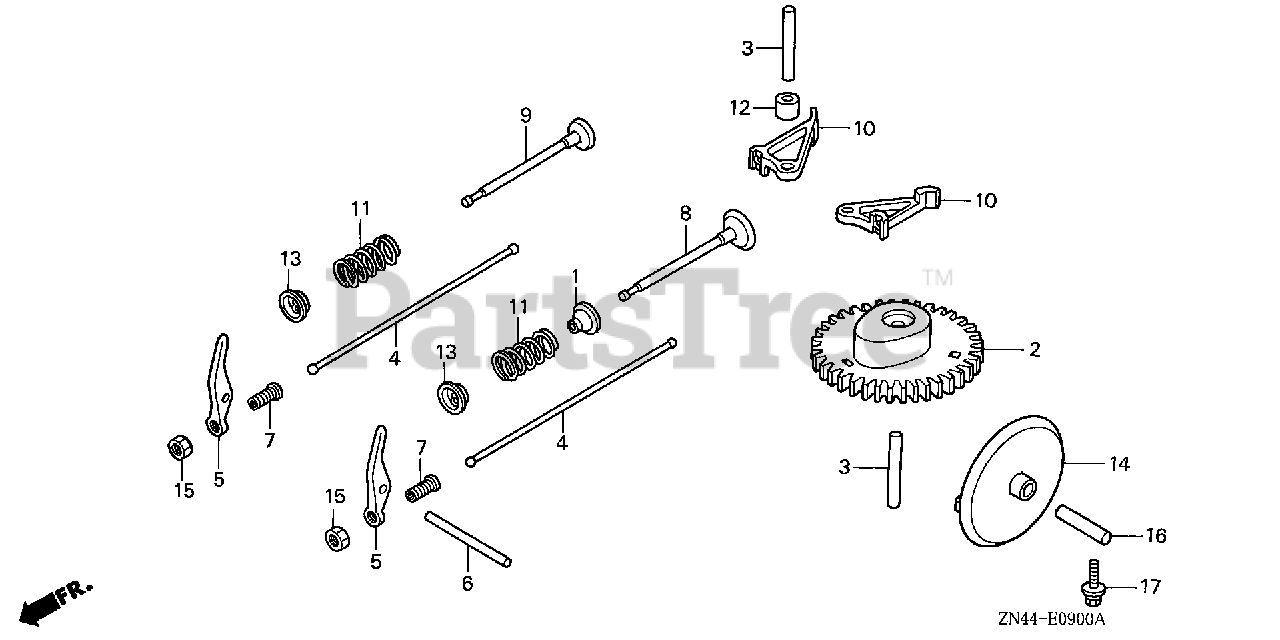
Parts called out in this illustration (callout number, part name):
1	SEAL, VALVE STEM
2	CAMSHAFT ASSY.
3	PIN, OIL PUMP
4	ROD, PUSH
5	ARM, VALVE ROCKER
6	ROLLER (4X37.8)
7	PIVOT, ROCKER ARM
8	VALVE, IN.
9	VALVE, EX.
10	LIFTER, VALVE
11	SPRING, VALVE
12	COLLAR, LIFTER
13	RETAINER, VALVE SPRING
14	SLINGER, OIL
15	NUT, TAPPET ADJ.
16	ROLLER (6X25)
17	BOLT-WASHER (5X16)
